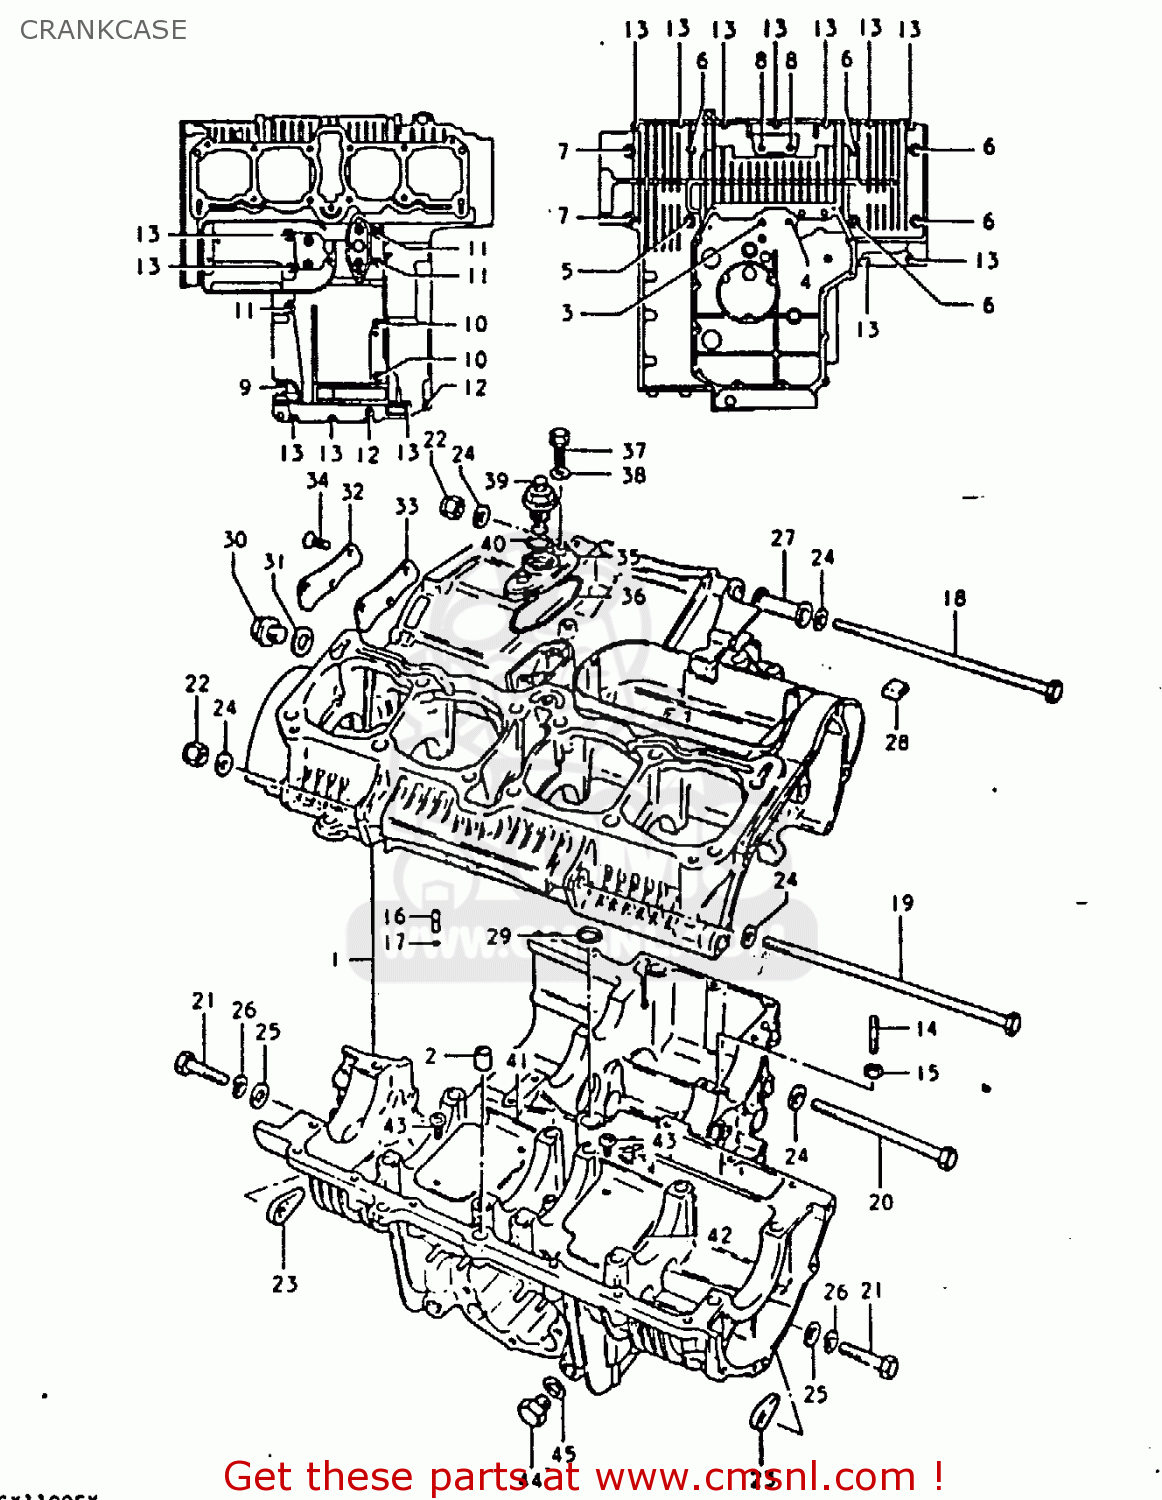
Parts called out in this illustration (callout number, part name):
1	CRANKCASE SET
2	PIN
3	BOLT
4	BOLT
5	BOLT
6	BOLT 8X90
7	BOLT 8X65
8	BOLT
9	BOLT
10	BOLT
11	BOLT (6X75)
12	BOLT
13	BOLT
14	STUD BOLT
15	NUT
16	UNION
17	O RING(D:1.05,ID:3.1)
18	BOLT 10X230
19	BOLT 10X250
20	BOLT(10X165)
21	BOLT 10X60
22	NUT
23	NUT
24	WASHER
25	WASHER(10.5X20X3.2)
26	LOCK WASHER
27	SPACER,ENGINE MOUNT
28	PAD,CYLINDER
29	O RING(D:3.2,ID:12.9)
30	PLUG (14X12)
31	GASKET(14X19.2X2) (NAS)
32	CAP,OIL GALLERY
33	GASKET,OIL GALLERY (MCA)
34	SCREW
35	HOUSING,OIL PRESSURE SWITCH
36	O RING,PRESSURE SWITCH HOUSING
37	BOLT
38	GASKET (NAS)
39	SWITCH ASSEMBLY
40	O RING(D:1.9,ID:18.8)
41	PLATE,OIL SEPARATOR
42	PLATE,OIL SEPARATOR
43	SCREW
44	PLUG
45	GASKET 14X18X1.5
